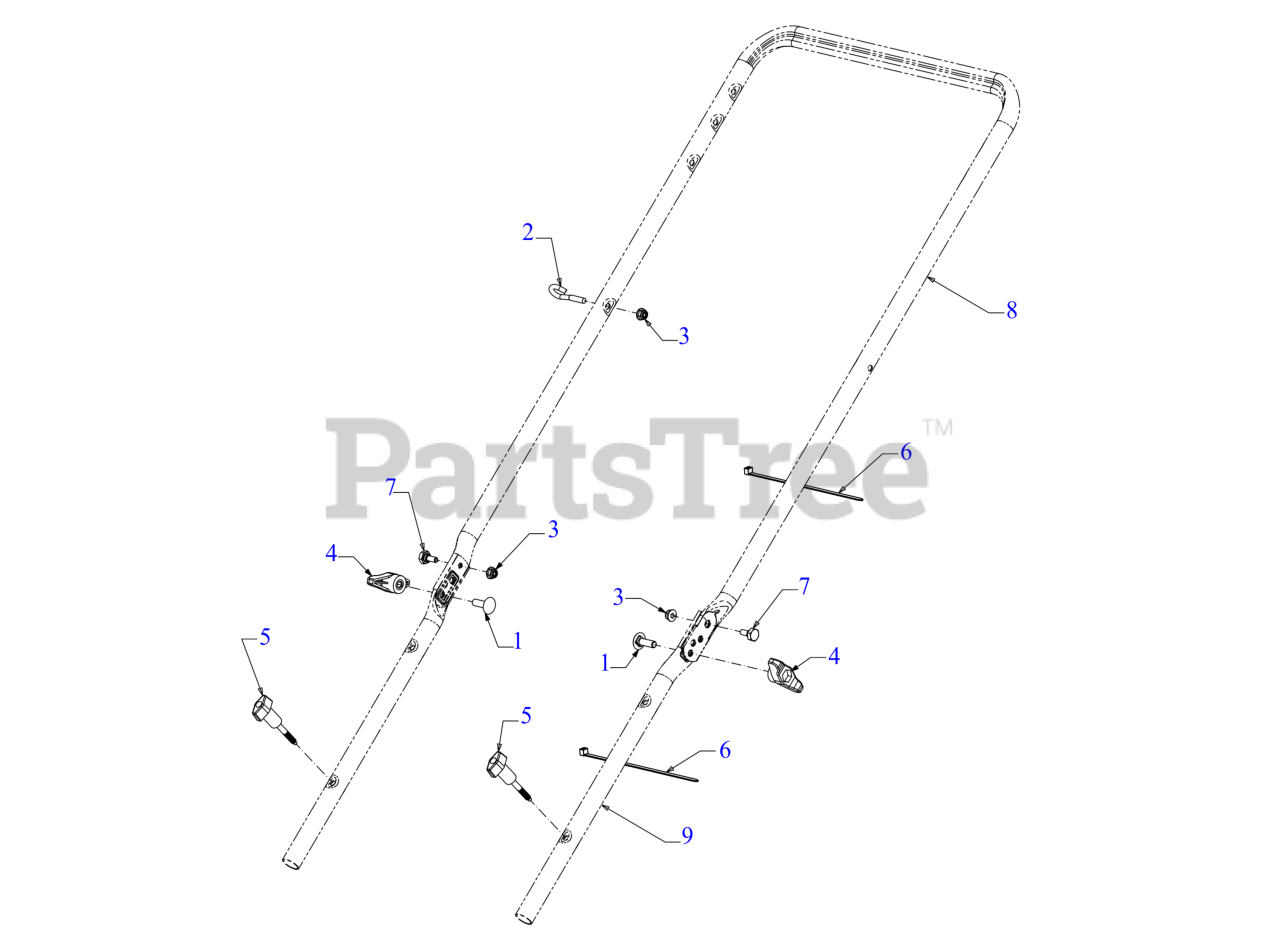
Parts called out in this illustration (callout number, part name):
1	SCREW 5/16-18 x 1.00 GR5
2	EYEBOLT 1/4-20
3	FLANGE LOCK NUT
4	WING KNOB 5/16-18
5	WING KNOB 1/4-20
6	7" CABLE TIE
7	SHOULDER SCREW
8	NON ADJUST UPPER HANDLE (POWDER BLACK)
9	LOWER HANDLE
